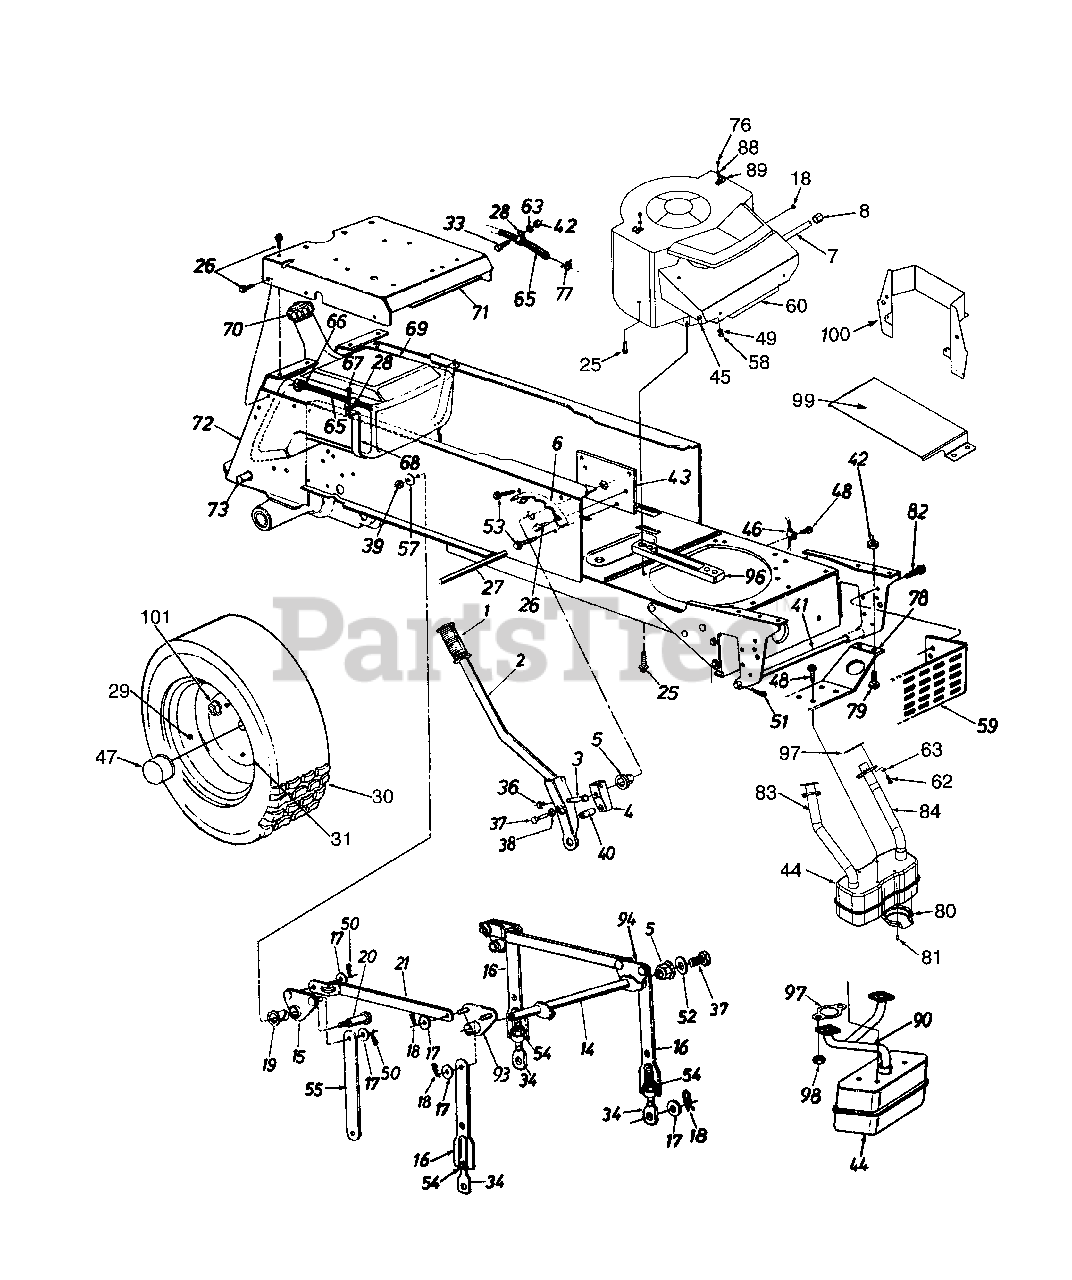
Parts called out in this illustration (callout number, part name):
1	Grip
4	Lift Shaft Drive
5	Plastic Hex Brg. 5/8" I.D.
8	Oil Drain Cap
14	Lift Shaft Ass'y.
15	Lift Pivot Brkt. Ass'y.
17	Fl-Wash. 1/2" I.D. x 1.00" O.D. x .090"
18	Hairpin Cotter
19	Flange Brg. .63" I.D.
20	Shld. Bolt 5/8" Dia. x .96" Lg. 3/8-16
26	Hex Thd. Rolling Scr. 5/16-18x .75" Lg.
27	Running Board Rod
28	Clamp
29	Air Valve
33	Hex Bolt 1/4-20 x .62" Lg.
34	Eye Bolt Adj. Link 1/2-13 Thd.
36	Hex Cent. L-Nut 5/16-18 Thd.
37	Hex Bolt 5/16-24 x .62" Lg.
39	Hex Top L-Nut 3/8-16 Thd.
40	Compression Spring
41	Deck Connecting Rod
42	Hex Sems Nut 1/4-20 Thd.
45	Hex Bolt 5/16-18 x .75" Lg.
46	Mounting Clamp
47	Hub Cap
48	Hex TT-Tap Scr. 1/4-20 x .5" Lg.
49	L-Wash. 5/16" I.D.
50	Cotter Pin .09 Dia. x 1.0" Lg.
51	Int. Cotter Pin
52	Flat Wash. .34" I.D. x 1.12" O.D. x .125"
53	Hex AB-Tap Scr. 5/16-24 x .5"
54	Hex Nut 1/2-13 Thd.
57	Bell-Wash. .4" I.D. x 1.13" O.D.
58	Hex Nut 5/16-18 Thd. (Gr. 5)
63	L-Wash. 1/4" I.D.
65	Fuel Line 60" Lg.
66	Hose Clamp
67	Hex AB-Tap Scr. 1/4 x .62" Lg.
68	Fuel Tank Strap
69	Gas Tank
70	Gas Gauge
71	Seat Plate
76	Truss Mach. B-Tap Scr. #10 x .5" Lg.
77	Hose Clamp
78	Muffler Mounting Brkt.
79	Hex Bolt 1/4-20 x .62" Lg.
80	Muffler Deflector
81	Hex F-Tap Scr. #8 x .32" Lg.
82	Hex TT-Tap Scr. 5/16"-18 x .62"
83	Exhaust Tube-R.H.
84	Exhaust Tube-L.H.
88	Fl-Wash. .188" I.D. x .438" O.D.
89	Clamp
90	Exhaust Pipe
93	Pivot Brkt. Ass'y.-R.H.
94	Pivot Brkt. Ass'y.-L.H.
96	Engine Mtg. Spacer
97	Gasket
98	Flange Nut M8 x 1.25 Thd.
99	Lower Heat Shield
